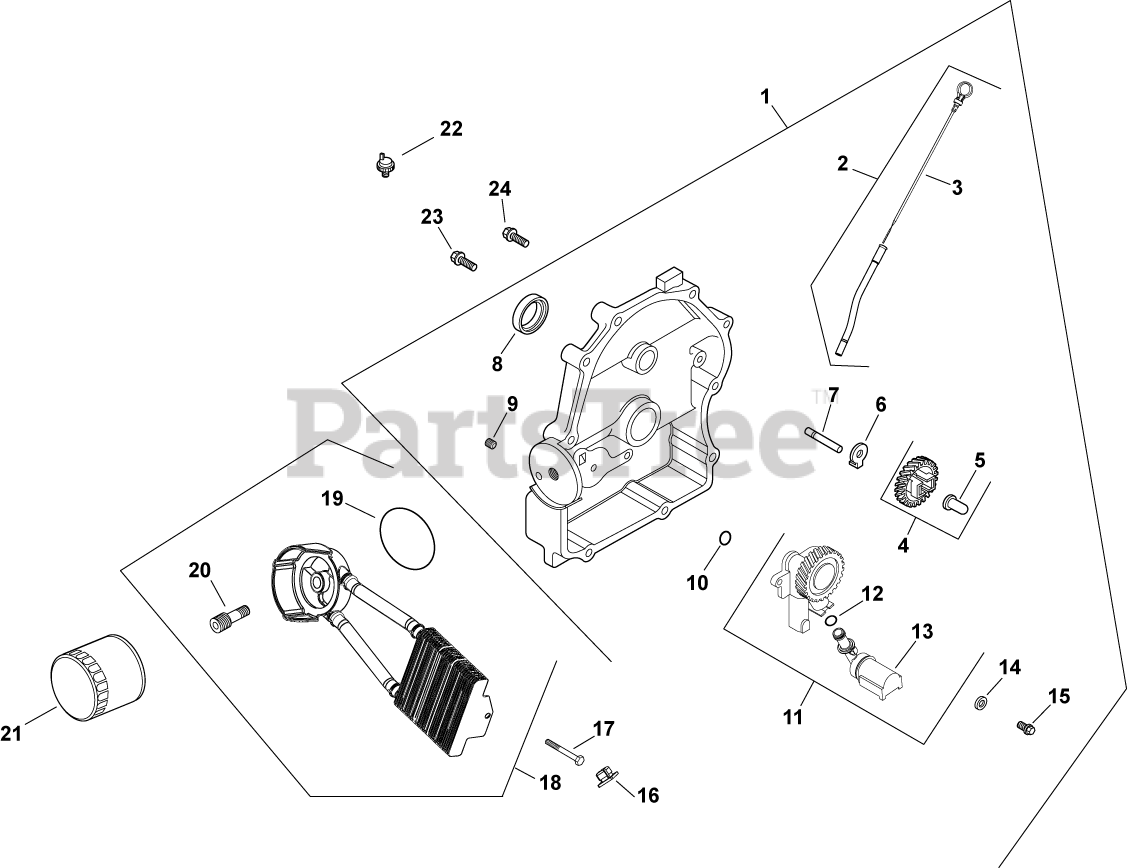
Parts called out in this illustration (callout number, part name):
1	PLATE, CLOSURE & BEARING USE 24 009 216-S
2	KIT, DIPSTICK/DIPSTICK TUBES
4	KIT, GOVERNOR GEAR W/PIN
5	PIN, GOVERNOR REGULATING
6	TAB, LOCKING
7	SHAFT, GOVERNOR GEAR
8	SEAL, OIL (KM)-USE 25 032 06-S
9	PLUG, CTSK PIPE 1/8"
11	PUMP ASSEMBLY, OIL-USE 24 393 53-S
12	O-RING, OIL PICK-UP
13	PICK-UP, OIL
14	WASHER, FLAT 6 MM
15	SCREW,FLG THD FRM M6X1.0X25-(#25086395S)
16	NUT, PLASTIC (KM)-USE 25 100 37-S
17	SCREW, TAP M6X1.7X18
18	KIT, OIL COOLER
19	O-RING, OIL COOLER
20	NIPPLE, OIL FILTER
21	OIL FILTER
22	SWITCH, PRESSURE (CLOSED)-USE 25 099 27-
23	SCREW, HEX FLANGE -USE 24 086 17-S
24	SCREW, FLG M8X1.25X45
